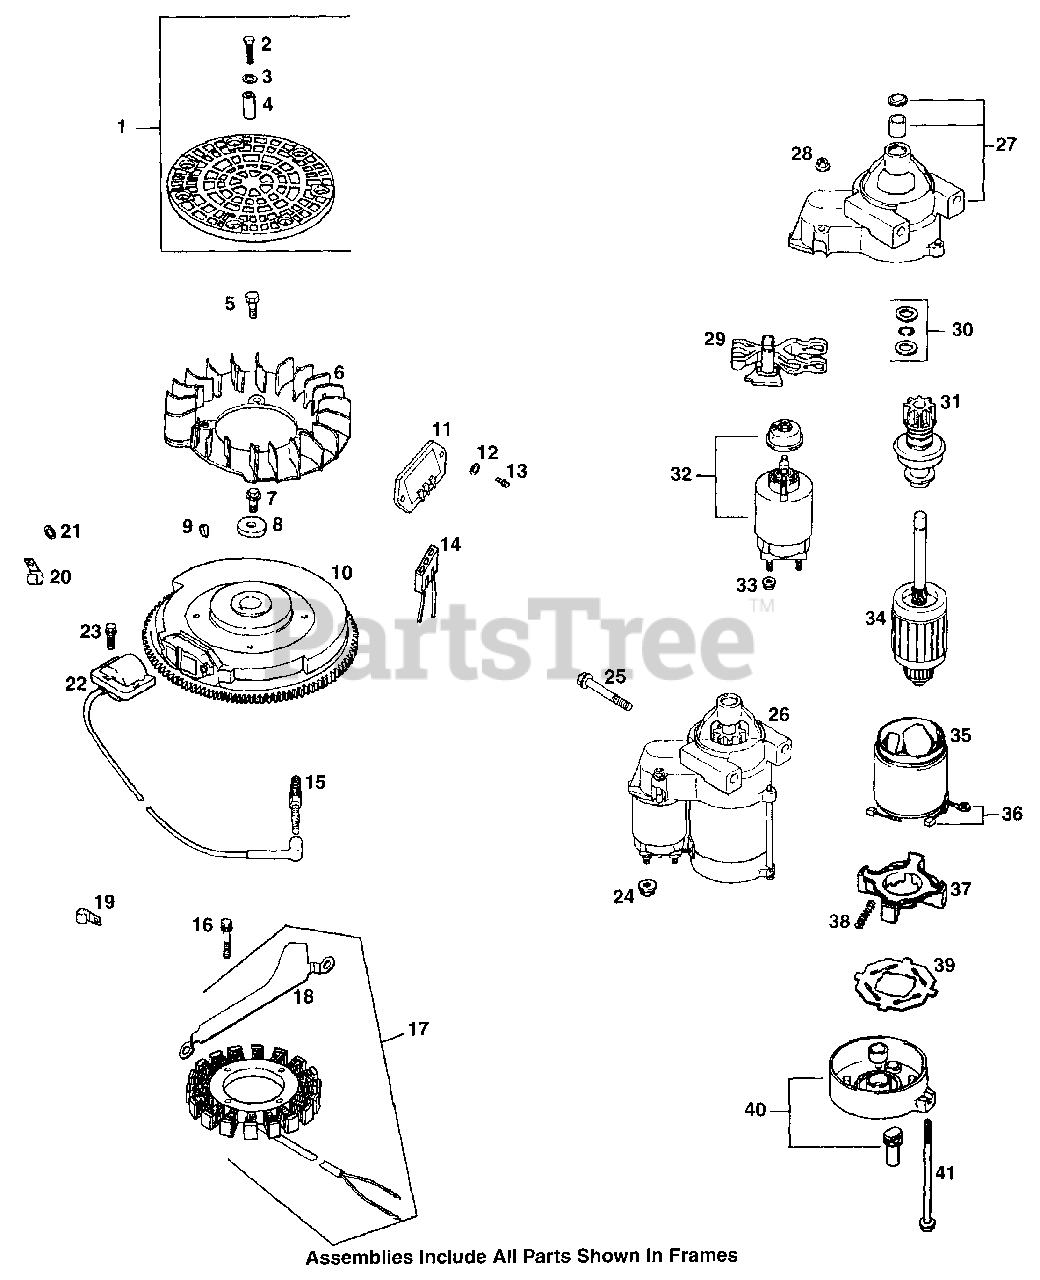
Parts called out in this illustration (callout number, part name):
1	Grass Screen Kit
2	Hex Cap Screw, M4 x.7 x 25
3	Washer, 5/16
4	Grass Screen Spacer
5	Shoulder Bolt, M6 x 1.0 x 16
6	Fan
7	Hex Flange Screw, M10 x 1.5 x 46
9	Key
10	Flywheel
11	Regulator Rectifier
12	Washer, 3/16
13	Phillips Head Screw, 11-16 x 7/8
14	Three Contact Connector
15	Spark Plug
16	Hex Cap Screw, M5 x .8 x 25
17	Stator Kit, 15A
18	Stator Wire Bracket
19	Cable Clip
21	Washer, 1/4
22	Ignition Module
23	Hex Flange Screw, M5 x .8 x 20
24	Hex Flange Nut, M8 x 1.25
25	Hex Flange Screw, M8 x 1.25 x 80
26	Starter Assembly
27	Drive End Cap
30	Starter Repair Kit
31	Pinion Drive
37	Brush Holder
38	Brush Spring
39	Starter Insulator
40	Commutator End Cap
